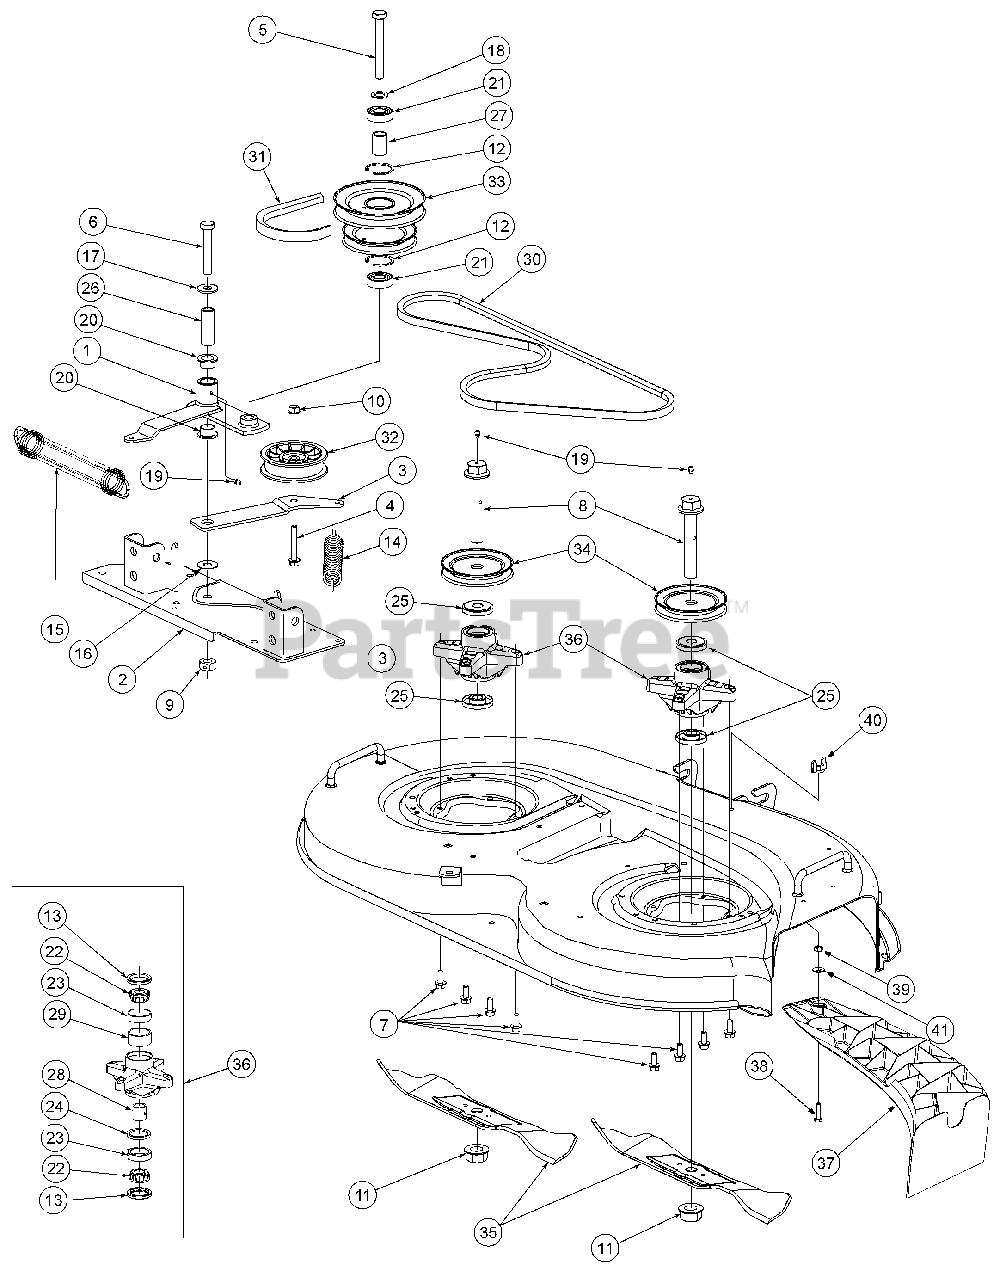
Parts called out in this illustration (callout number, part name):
2	Plate, Mounting
4	Screw, Hex Cap, 3/8-16 x 1.5 GR5
5	Screw, Hex Cap, 5/8-18 x 3.0 GR5
6	Screw, Hex Cap, 1/2-20 x 3.0 GR8
7	Screw, Hex Wsh Hd Tap, 5/16-18 x .75
8	Bolt, Spindle, 3/4-16 x 4.25
9	Nut, Hex Center Lock, 1/2-20
10	Nut, Hex Flange Lock, 3/8-16
11	Nut, Hex Flange, 3/4-16
12	Snap Ring, Internal
13	Seal, Oil, 1.25 x 1.874 x .25
14	Spring, Extension, .88 x 6.12
15	Spring, Extension, 1.25 x 8.15
16	Washer, Flat, .531 x 1.25 x .036
17	Washer, Flat, .531 x 1.25 x .100
18	Washer, Flat, .63 x 1.0 x .063 Hdn
19	Fitting, 3/16 Drive Lube
20	Bearing, Flange, 3/4 ID x .53 Lg
21	Bearing, Ball, .62 ID x 1.57 OD
22	Cone, Bearing
23	Cup, Bearing
24	Spacer, Bearing
25	Spacer, Deck Spindle
26	Spacer, Idlr Brkt .50 ID x .75 OD x 2.25
27	Spacer, Pully .635 ID x .88 OD x 1.25
28	Spacer, Bearing, .780 x .963 x .777
29	Spacer, Bearing, 1.615 x 1.86 x .8427
30	Belt, Spindle, A-Section x 61 Lg
31	Belt, PTO, B-Section x 112.4 Lg
32	Pulley, Flat Idler, 3.5 OD
33	Pulley, Double
34	V-Pulley, 4.0 Dia
35	Blade, 3 In One, 21.20 Lg
36	Spindle Assembly, Blade
37	Plug, Mulch
38	Screw, Hex Cap, 1/4-20 x 1.0 GR5
39	Nut, Hex, 1/4-20 GR5
40	Nut, Wing, 1/4-20
41	Washer, Flat, .28 x .74 x .063
